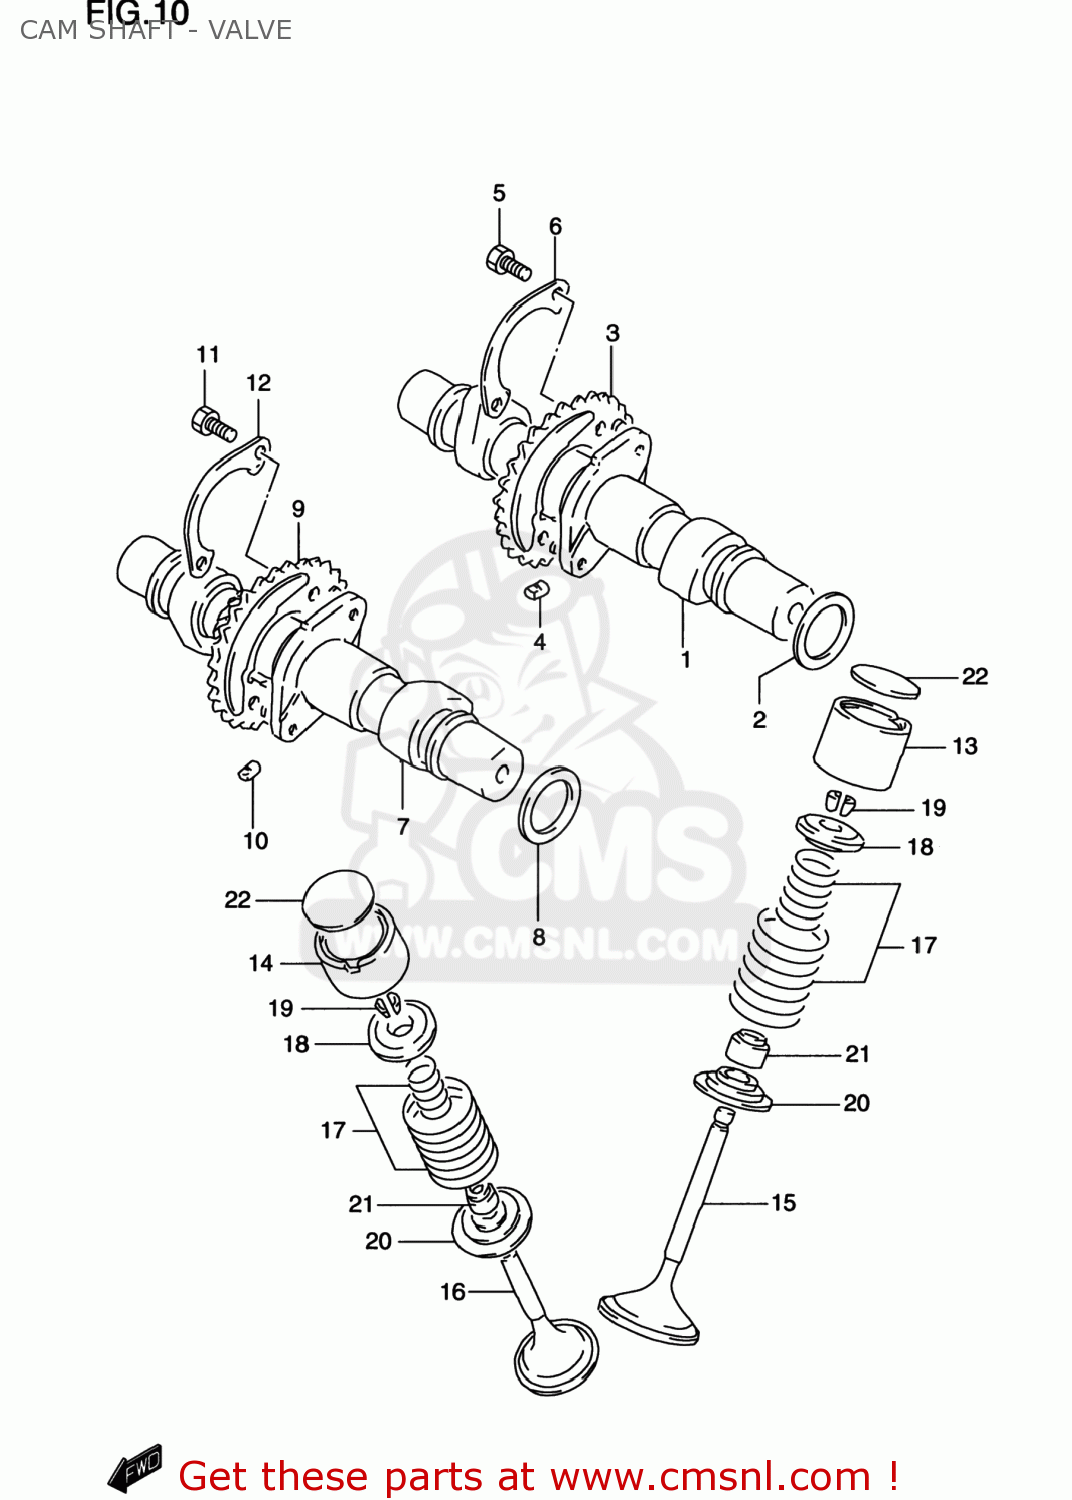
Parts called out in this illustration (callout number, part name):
1	CAMSHAFT SET,INTAKE
2	SHIM(22X30X1)
3	SPROCKET,CAMSHAFT INTAKE
4	PIN,SPROCKET
5	BOLT(6X12.5)
6	WASHER,CAM CHAIN SPROCKET
7	CAMSHAFT SET,EXHAUST
8	SHIM(22X30X1)
9	SPROCKET,EXHAUST CAM(NT:30)
10	PIN,SPROCKET
11	BOLT(6X12.5)
12	WASHER,CAM CHAIN SPROCKET
13	TAPPET
14	TAPPET
15	VALVE,INTAKE
16	VALVE,EXHAUST
17	SPRING SET,VALVE
18	RETAINER,VALVE SPRING
19	COTTER VALVE
20	SEAT,VALVE SPRING
21	SEAL,OIL(7X14.4X9)
22	SHIM,TAPPET(T:2.15)
23	SHIM SET,TAPPET
24	CASE,SHIM
